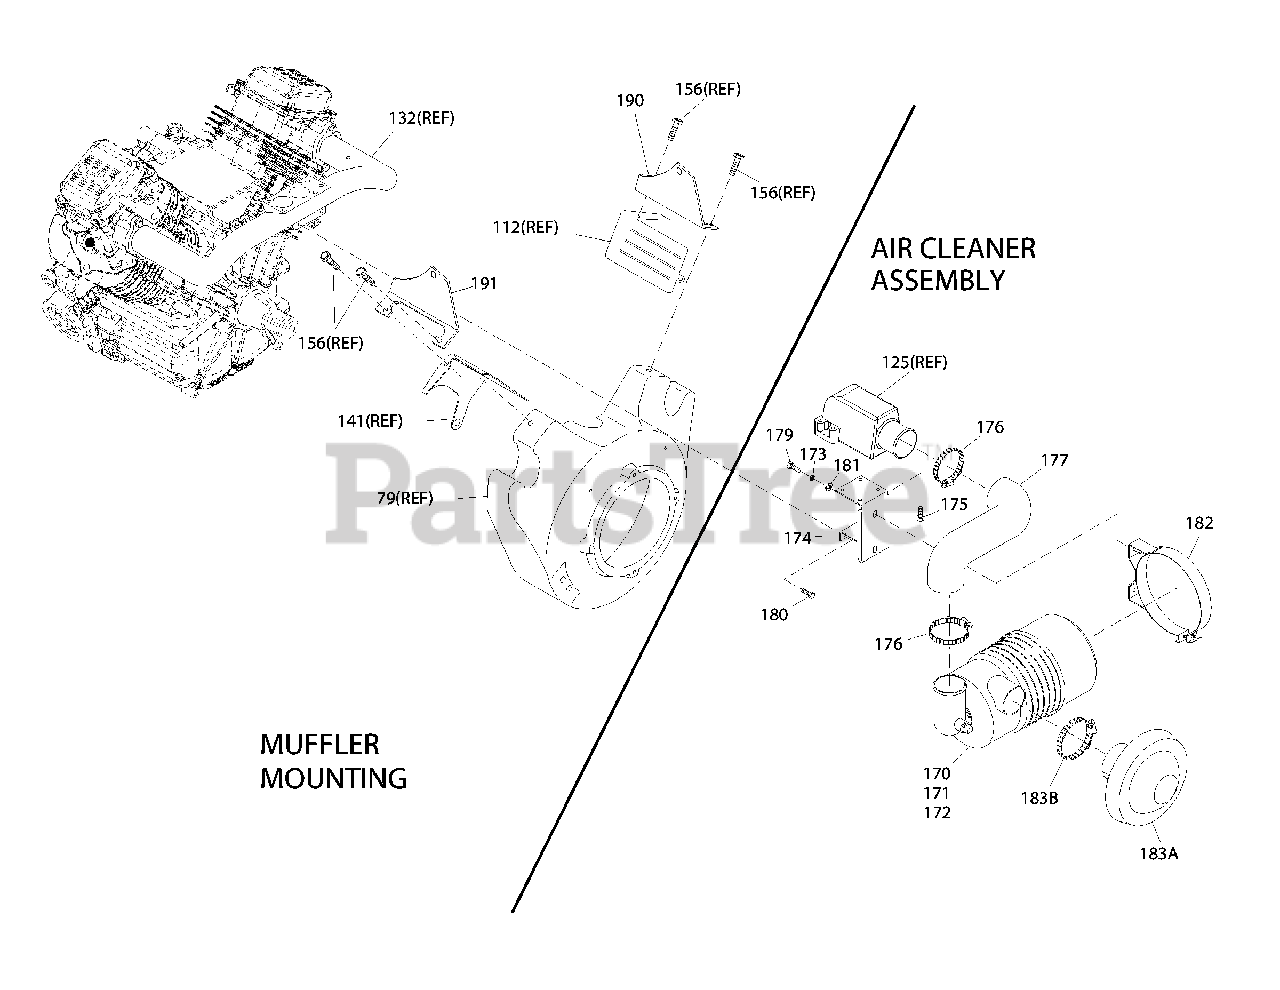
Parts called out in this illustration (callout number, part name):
170	CLEANER, AIR W/SFTY FLT
171	FILTER, AIR PRIMARY
172	FILTER, AIR SAFETY (INNER)
173	WASHER LOCK M8-5/16
174	BRKT, AIR CLEANER SUPPORT
175	SCREW BHSC M6-1.0 X 12 SS
176	CLAMP HOSE #32 1.563-2.500
177	HOSE AIR CLEANER
179	SCREW HHC M8-1.25 X 16 G8.8
180	SCREW HHFC M6-1.0 X 10 G8.8
181	WASHER FLAT 5/16-M8 ZINC
182	ASSY, BAND MOUNT AIR CLEANER
183A	HOOD, INLET
183B	CLAMP, HOSE
190	SUPPORT, MUFFLER LH
191	SUPPORT, MUFFLER RH
